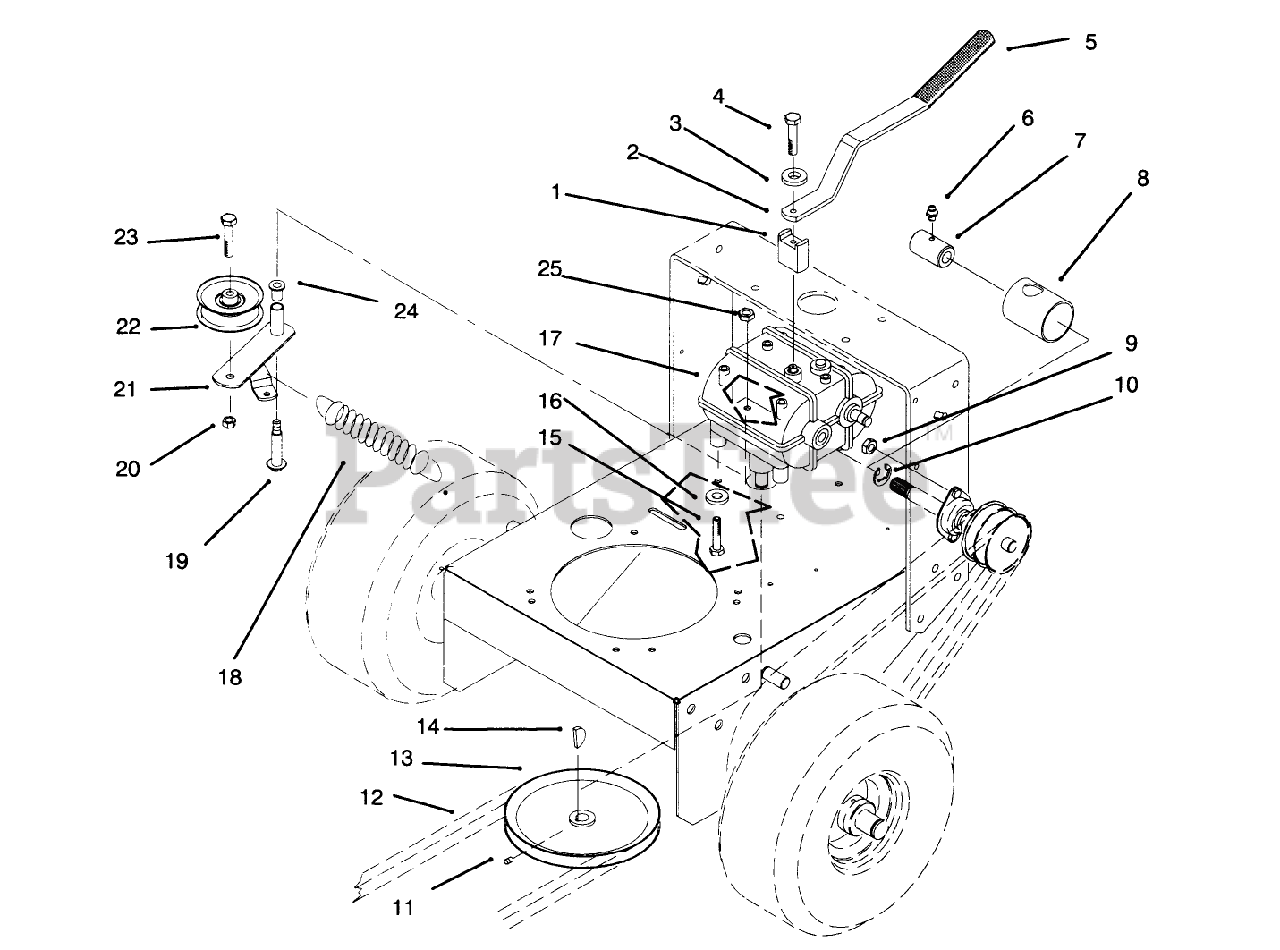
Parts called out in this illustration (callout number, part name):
1	MOUNT-LEVER, SHIFT
2	Lever-Shift
3	SPACER
4	SCREW-HH
6	FITTING-GREASE
7	COUPLER
8	GUARD-COUPLER
9	NUT-LOCK, NI
10	RING-SNAP, EXTERNAL
11	SCREW-SET, HSH
12	V-BELT
13	PULLEY-DRIVEN
15	SCREW-HH
16	WASHER-LOCK
17	TRANSMISSION
18	SPRING
19	BOLT-WHEEL
20	NUT-LOCK, NI
21	Lever-Idler (Incl. Ref. #24)
22	PULLEY
23	SCREW-HH
24	BUSHING-FLANGE
25	NUT-LOCK
